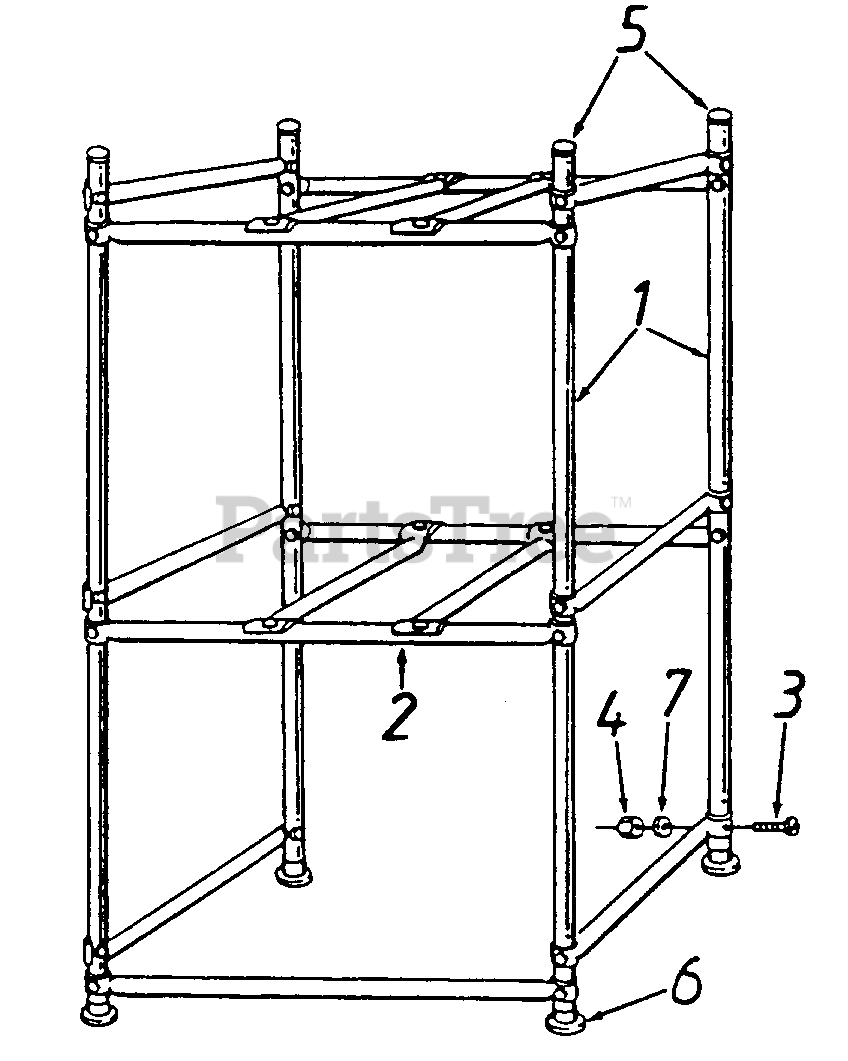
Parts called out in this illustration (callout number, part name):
4	Hex Nut 1/4-20 Thd.
5	1" Tubing Plug (Installed)
6	1" Swivel Guide (Installed)
7	Lock Washer 1/4" I.D.
